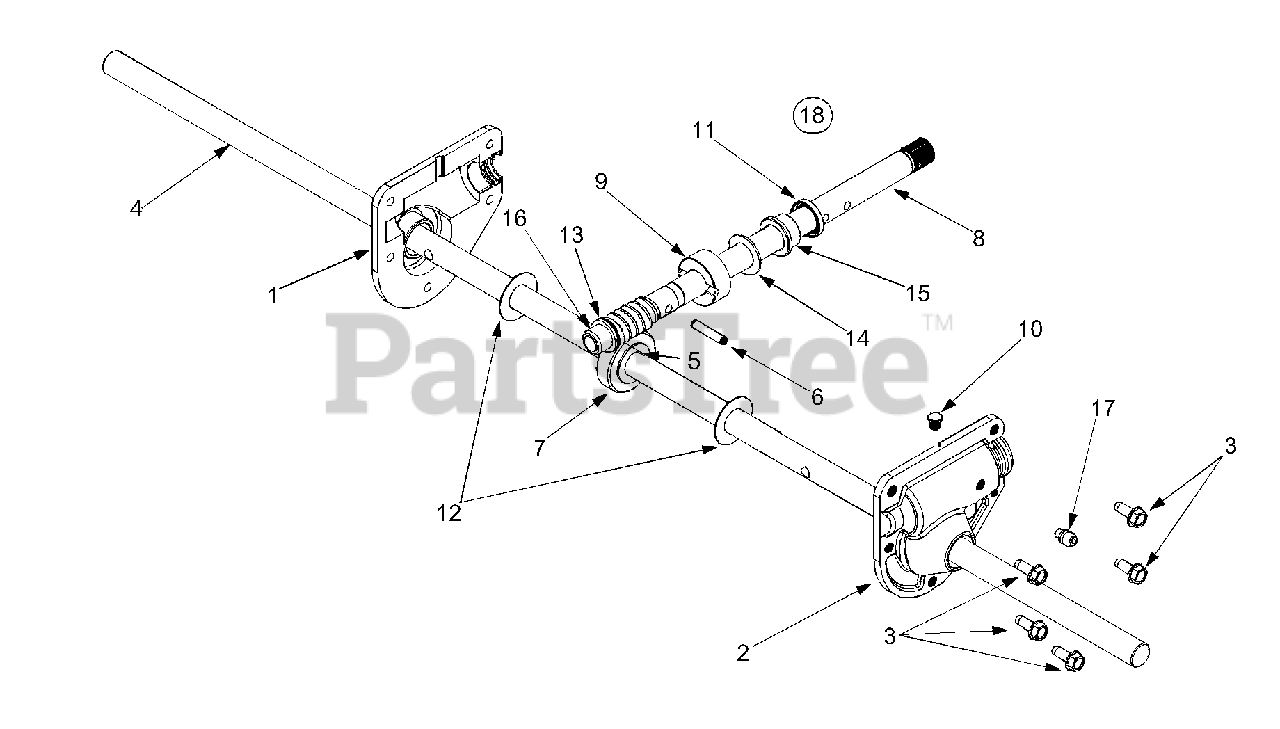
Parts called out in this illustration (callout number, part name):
1	RH Housing
2	LH Housing
3	Self Tapping Screw, 1/4-20 x.75
4	Spiral Axle 28"
5	Hi-Pro Key, 3/16 x 5/8
6	Spring Spiral Pin,.25 x 1.25
7	Worm Gear, 20-tooth
8	Worm Shaft
9	Thrust Collar
10	Grease Plug
11	Grease Seal
12	Flat Washer,.76 x 1.5 x.030
13	Flat Washer,.508 x 1.0 x.020
14	Flat Washer,.76 x 1.5 x.060
15	Flange Bearing,.75 x 1.0 x.59
16	Flange Bearing,.503 ID x.75 OD
17	Lube Fitting, 3/16 Drive
18	Gear Assembly Complete, 28"
